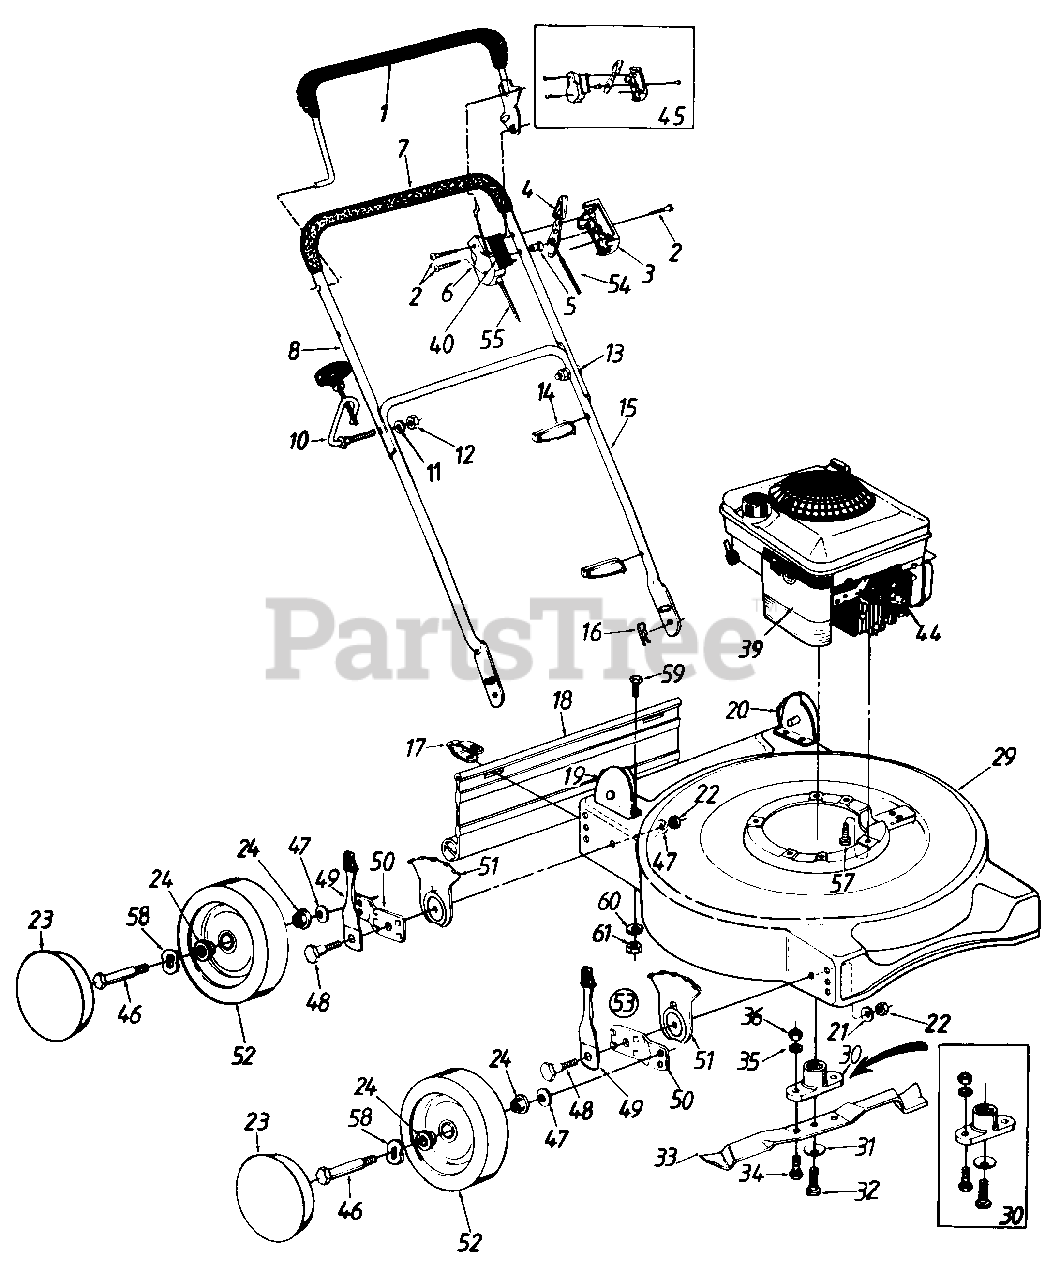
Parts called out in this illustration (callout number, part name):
1	Control Handle Ass'y.
2	Truss Mach. Scr. #12 x 1.5" Lg.
3	Control Panel Half
4	Throttle Control Lever
5	Control Disc Pin
6	Clutch Panel Half
7	Grip
8	Upper Handle
10	Rope Guide Bolt
11	L-Wash. 5/16" I.D.
12	Hex Nut 5/16-18 Thd.
13	Curved Carriage Bolt 5/16-18 x 1.38" Lg.
14	Cable Tie
15	Lower Handle
16	Hairpin Cotter
17	Hinge Clip
18	Rear Flap
19	Handle Bracket Ass'y. R.H.
20	Handle Bracket Ass'y. L-H
21	Bell-Wash. .39" I.D. x 1.38"
22	Hex Nut 3/8-16 Thd.
23	Hub Cap
24	Ball Bearing
29	20" Deck Ass'y.
30	Blade Adapter Kit (Splined)
31	Bell-Wash. .46" I.D.
32	Hex Bolt 7/16-20 x 1.5" Lg.
33	20" Mulching Blade
34	Hex Bolt 3/8-24 x 1" Lg.
35	L-Wash. 3/8" I.D.
36	Hex Nut 3/8-24 Thd.
39	Engine
40	Throttle Label
44	Spark Plug Boot
45	Kit Control Housing Comp.
46	Axle Bolt
47	Bell-Wash. .400" I.D. x .88"
48	Shld. Bolt .50" Dia. x .357"
49	Spring Lever Ass'y. w/Knob
51	Height Adj. Plate
52	Wheel Ass'y. Comp.
53	Height Adj. Ass'y. Comp. R.F. & L.R.
54	Throttle Cable 51"
55	Control Cable 35"
57	Hex L-Wash. Hd. Scr. 3/8-16 x 1.0" Lg.
58	Wave Washer .531" I.D.
59	Hex Bolt 1/4-28 x .75" Lg. (Grade 5)
60	L-Wash. 1/4" I.D.
61	Hex Nut 1/4-28 Thd.
